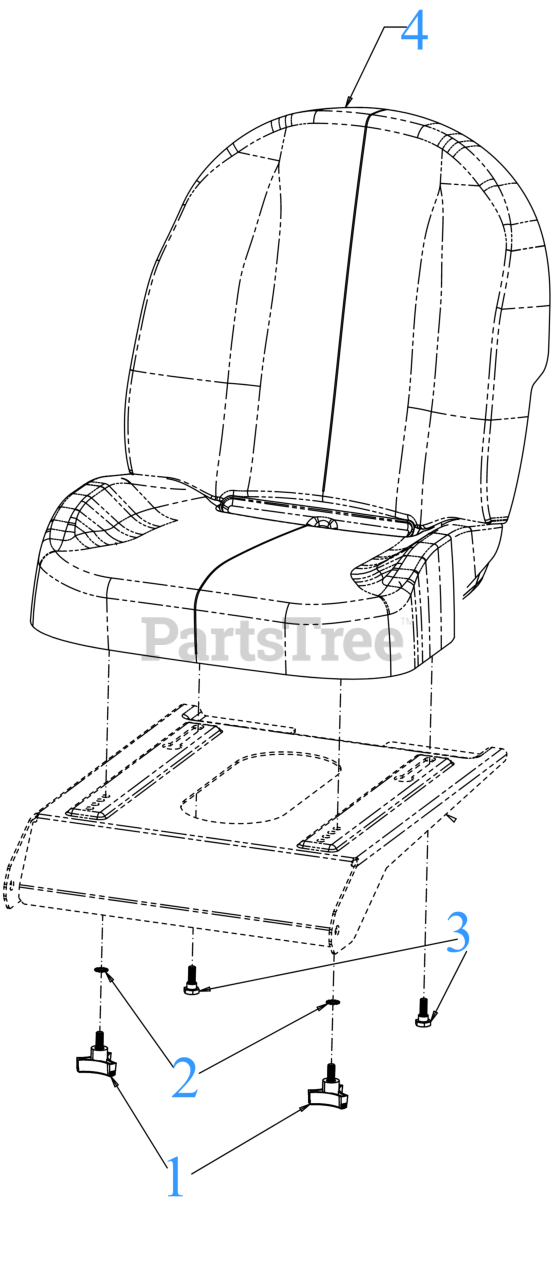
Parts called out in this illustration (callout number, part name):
1	3 PRONG KNOB 5/16-18
3	SHOULDER SCREW .437
3	FLAT WASHER ID-.320 x .598
4	18" SEAT (4 PT MTG)
